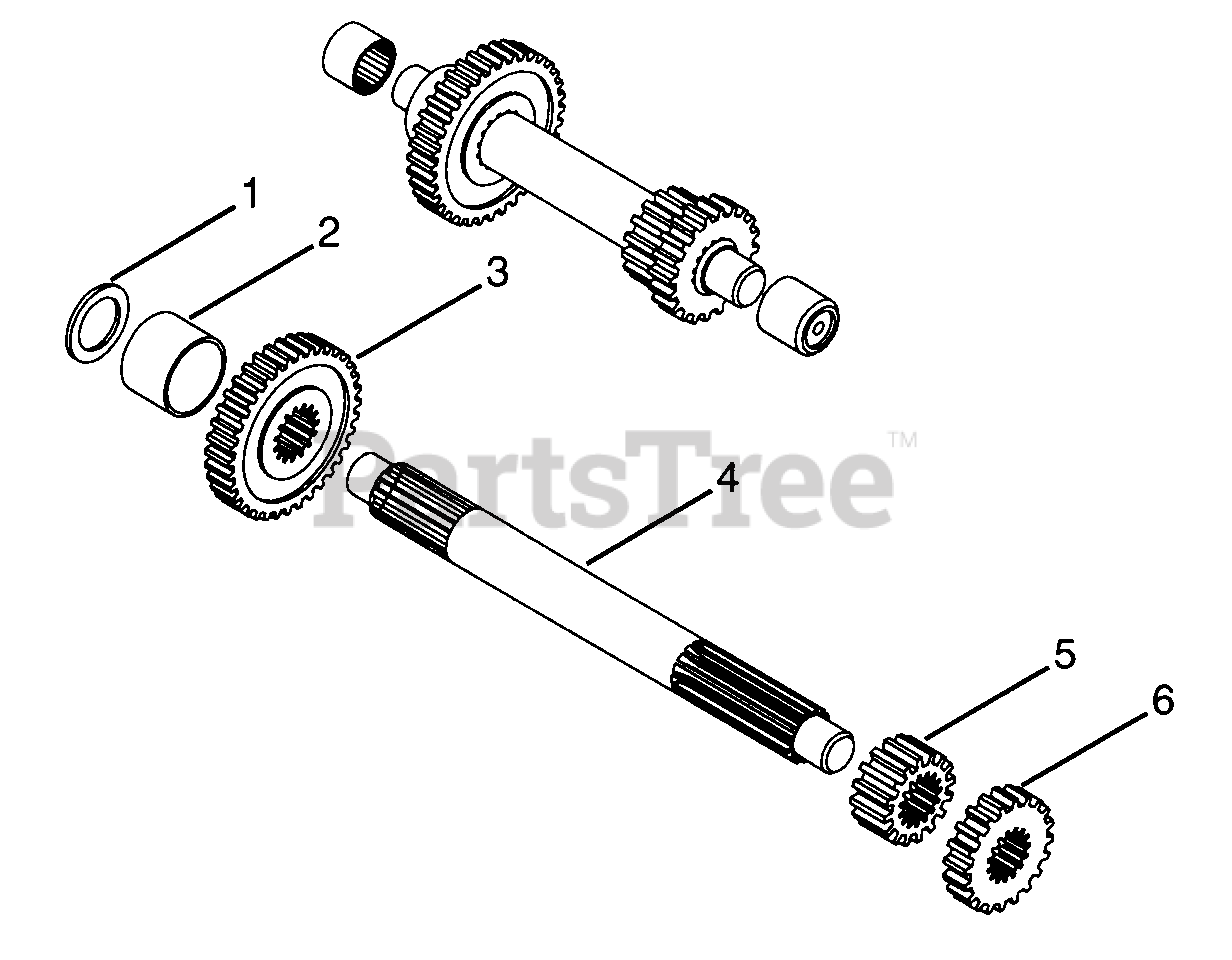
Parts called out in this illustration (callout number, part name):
1	Washer-Thrust .63 x 1.15 x .093
2	Bushing-Sleeve 1.03 x 1.13 x .457
3	Gear
4	Shaft-Splined
5	Gear 10 DP 16 Teeth x .750
6	Gear 10 DP 20 Teeth x .600
